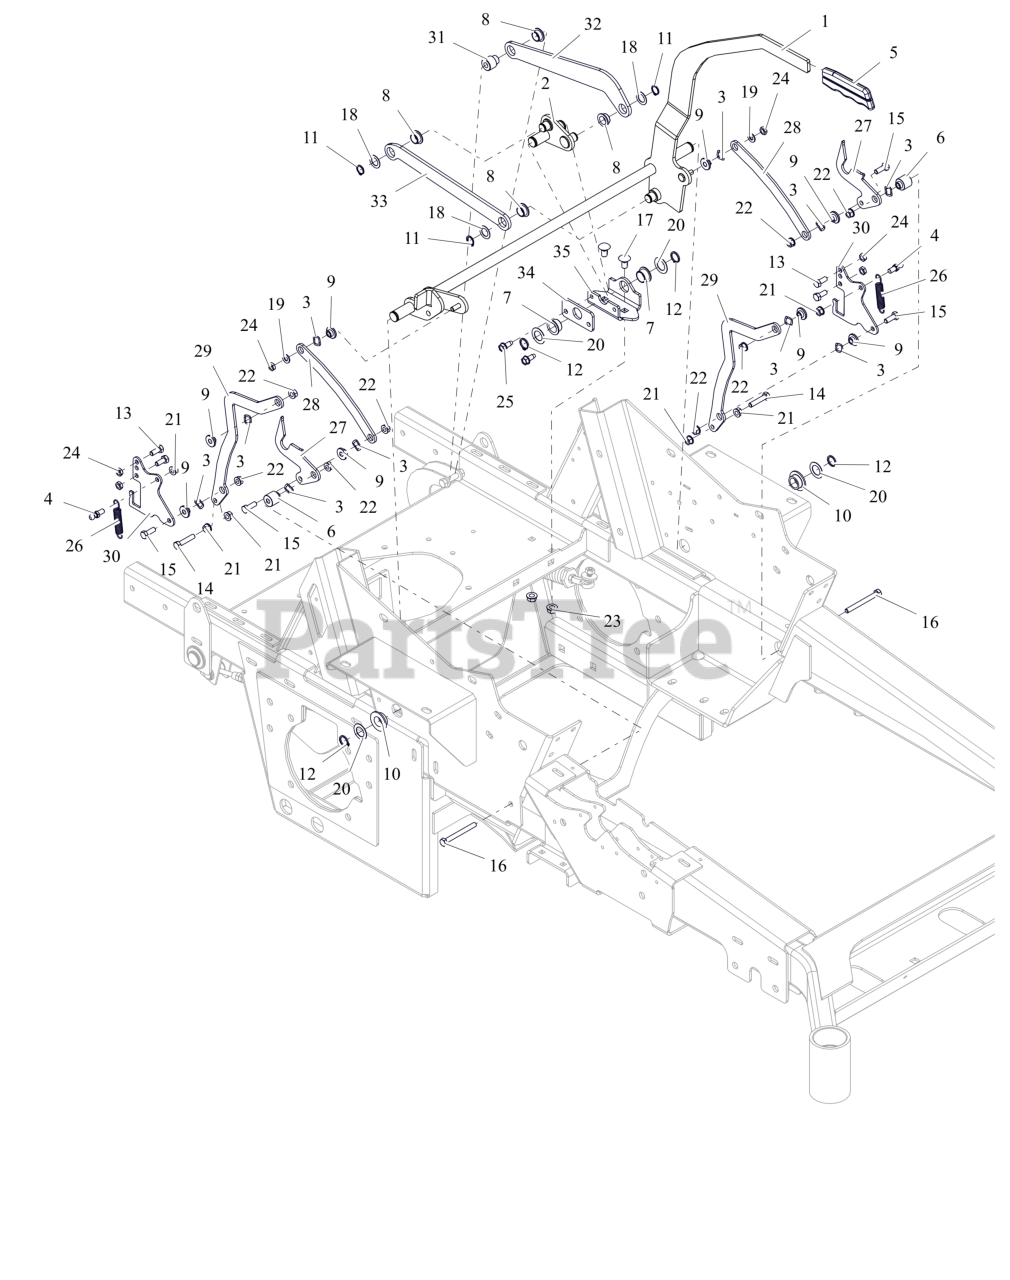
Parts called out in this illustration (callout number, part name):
1	WLDMT, PARKING BRAKE ARM (BLACK)
2	WLDMT, BRAKE ACTIVATION PIVOT
3	WAVE WASHER .531X.781X.125FH
4	STUD- BALL
5	GRIP, PARKING BRAKE (YELLOW)
6	BUSHING FLANGED - .318X.500X.972X.875
7	BSHG, FLANGE .750 X .875 X .5000 X 1.125
8	BSHG, FLANGE .625 X .750 X .375 X 1.000
9	BSHG-FLG .32X.500X.344X.880
10	BSHG-FLG .762X1.48X.44 NYL
11	RG-RTNG-EXT .625X.050
12	RG-RTNG-EXT .689X.078
13	BLT,HEX .31-18X.75 G5 ZCC
14	BLT, HEX .31-18X1.50 G5 ZCC
15	BLT, HEX .31-18X.875 G5 ZCC
16	BLT, HEX .31-18X3.00 G5 ZCC
17	BLT, RHSN .38-16X.750 G5 ZCC
18	WSHR-THRST .625 X 1.0 X .03
19	WSHR,FLT .344X.688X.065 ZCC
20	WSHR-HDND-THRST .758X1.23X.031
21	NUT,SPNLK-FLG .31-18 G5 ZCC
22	NUT,LK-CTR-FLG .31-18 GF ZCC
23	NUT-LK-CTR-FLG .375-16 GF ZCC
24	NUT-LK-CTR-JAM .312-18 GB ZCC
25	SCR,TAP .312-18X.75 HWH TR ZCC
26	SPRING,EXT,.061X.50X3.0
27	BRKT, BRAKE - RTN (BLACK)
28	BRKT, LINK - BREAK RTN (BLACK)
29	BRKT, LINK - SPEED CONTROL HTG
30	BRKT, SPEED - HTG (BLACK)
32	LINK, BRAKE ACTIVATION REAR
33	LINK, BRAKE ACTIVATING FRONT
34	PLATE, BSHG MOUNTING
35	BRKT, BSHG MTG
